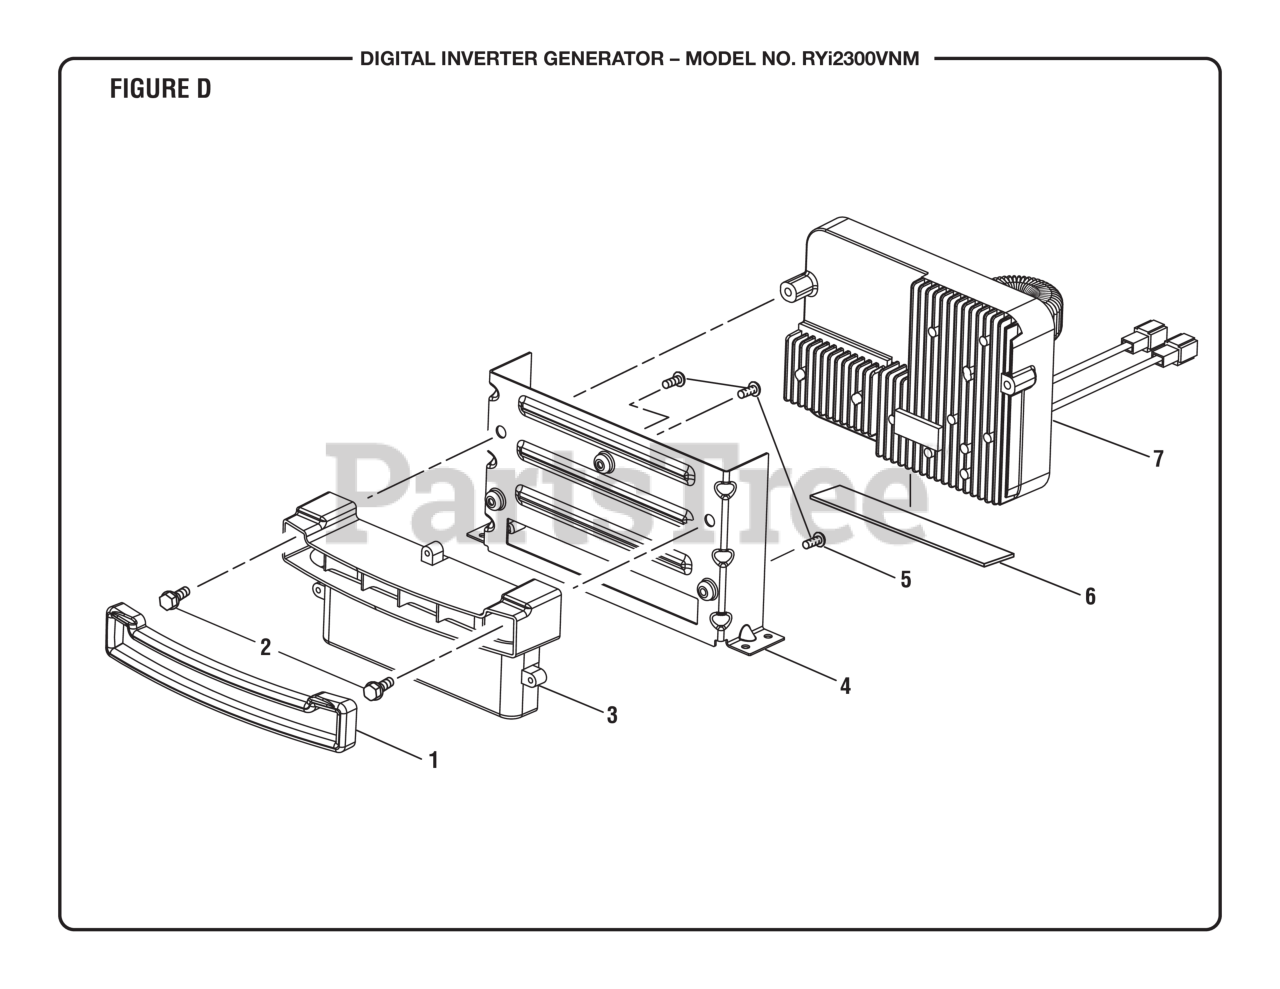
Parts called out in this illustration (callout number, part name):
1	Edge Trim Rubber
2	Bolt (M6 x 12 mm, Hex Hd.)
3	Baffle (Engine Intake)
4	Inverter Module Bracket
5	Screw w/Washer (M4 x 10 mm, T20 Torx Button Hd.)
6	Rubber Pad
7	2KW INVERTER MODULE WITH UART - LIHUA
